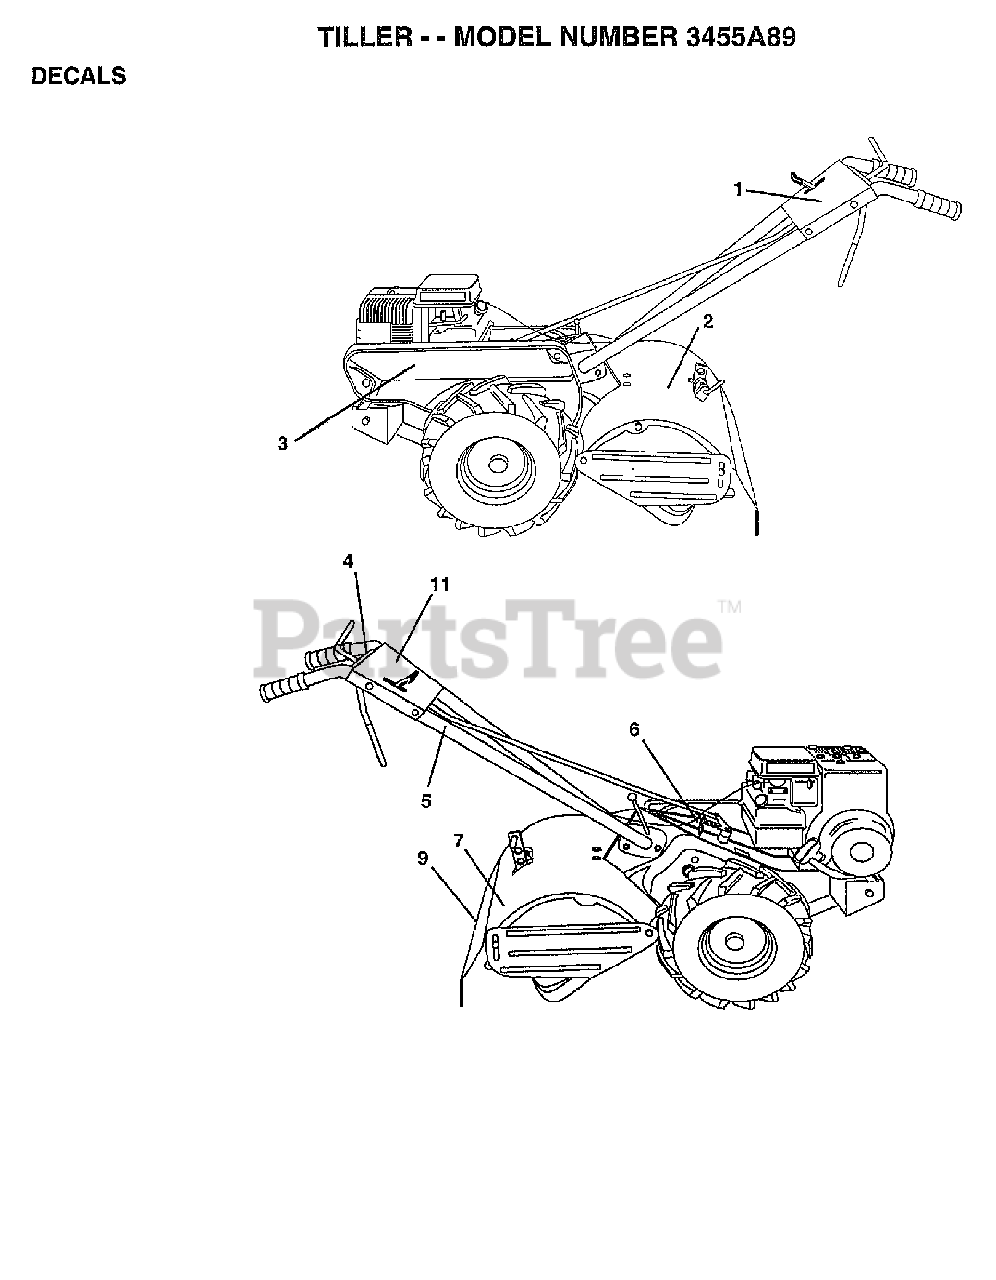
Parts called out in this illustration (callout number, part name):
1	Poulan TBD
3	Poulan TBD
5	DECAL, HAND PLACEMENT
6	DECAL.SHIFT.INDICATOR.TILLER
9	DECAL TI
